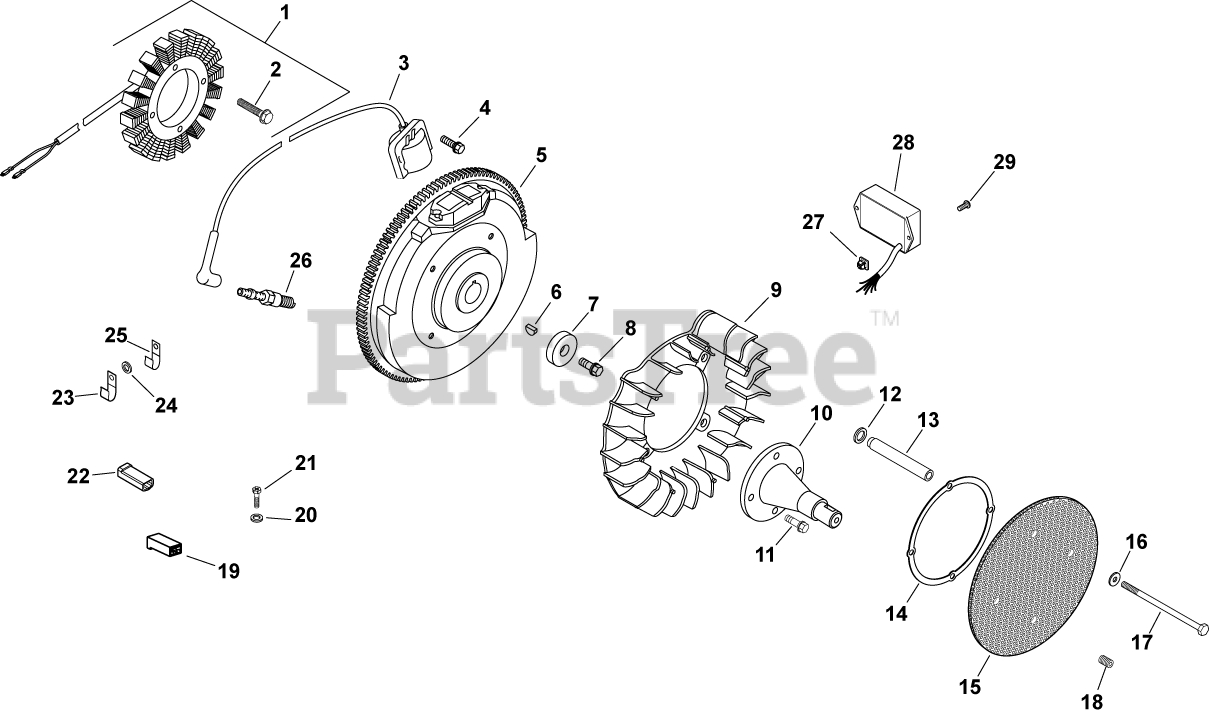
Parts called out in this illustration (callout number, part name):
1	STATOR - USE 28 085 02-S
2	SCREW, THD FROM M5X0.8X30
4	SCREW, SKT THD FRM M5X0.8X25
5	FLYWHEEL ASSEMBLY - USE 24 025 14-S
6	KEY, 3/16" X 5/8"
7	WASHER, FLAT 13/32"
8	SCREW, FLG M10X1.5X45 - (#25086361S)
9	FAN (WITH HOLE)-USE 24 157 16-S
10	SHAFT, FRONT DRIVE
11	SCREW, FLG M8X1.25X25
12	WASHER, FLAT 1/4" (O.D. 5/8")
14	RING, SUPPORT USE 25 141 08-S
16	WASHER, SPRING 10 MM
17	SCREW, CAP M6X1.0X99.5
18	SCREW, SKT SET #10-24X1/4"
19	CONNECTOR
20	WASHER, FLAT 3/16"
21	SCREW, PHL HD #11-16X7/8"
22	CONNECTOR (1 CONTACT)
23	CLIP, CABLE
24	WASHER, FLAT 1/4" (O.D. 1/2")
26	PLUG, SPARK (STD)
27	NUT, PLASTIC
28	MODULE, SPEED ADVANCE
29	SCREW, PHL HD #11-16X1/2"
1245403-S	TIE, CABLE
2545403-S	TIE, WIRE
X-22-10-S	WASHER, INT TOOTH LOCK 3/8"
